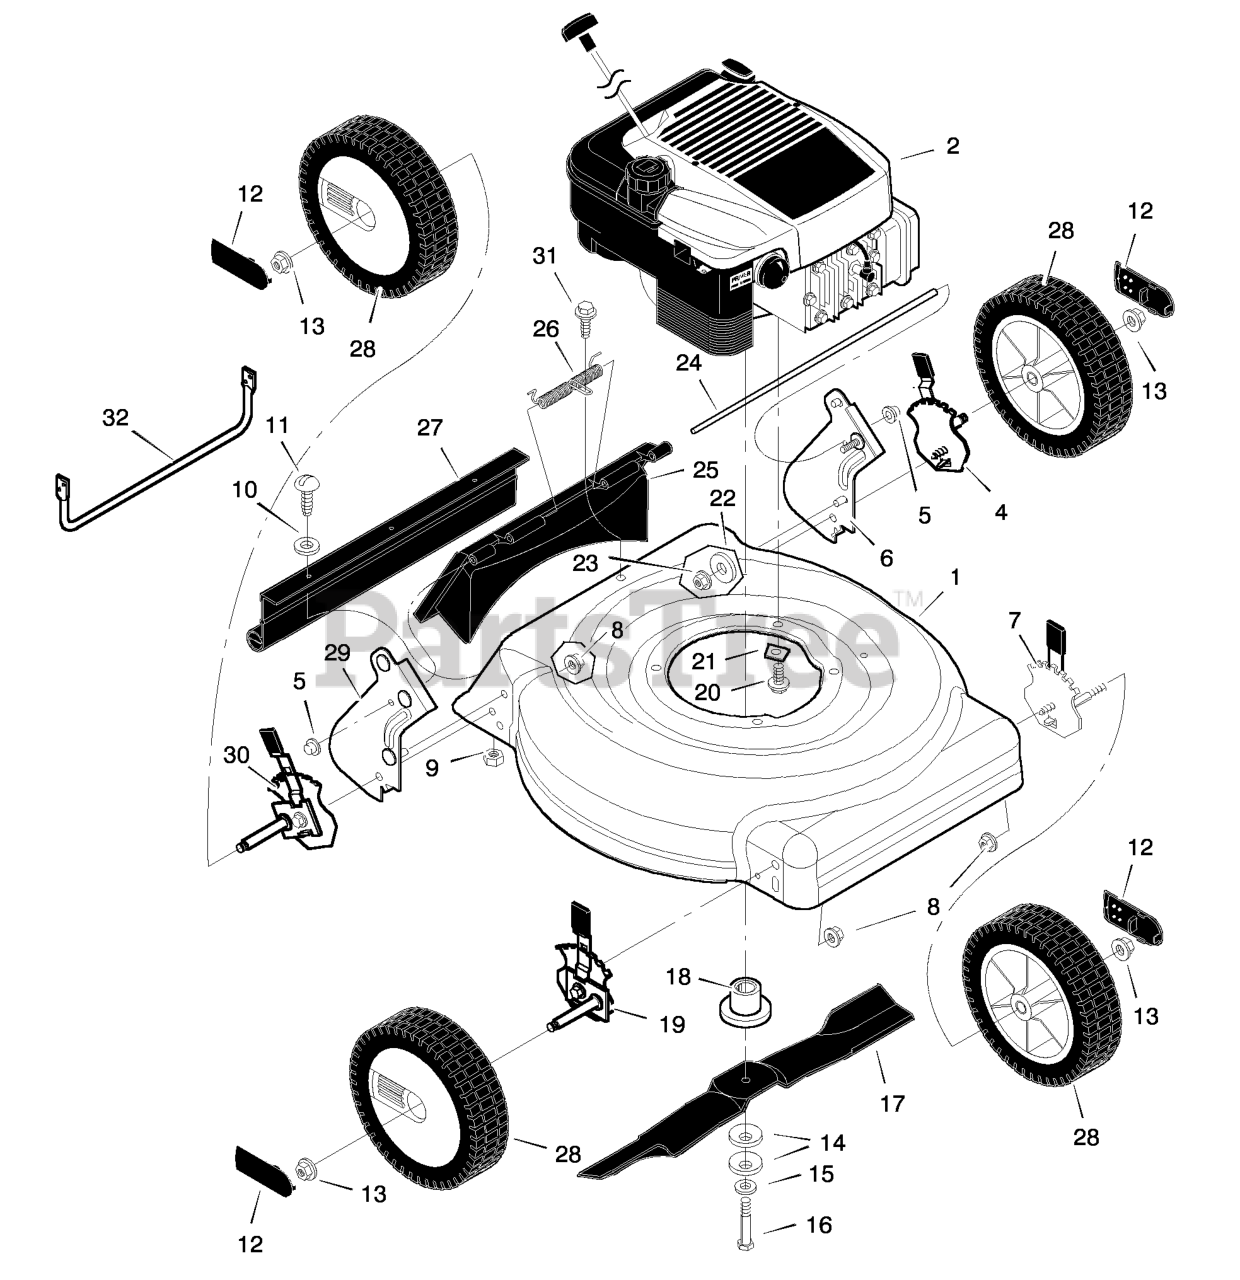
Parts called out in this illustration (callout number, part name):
1	Housing
2	Engine
3	Stop, Rope (Recoil - Start)
4	Adjuster, Left Rear Height
5	Push On Cap
6	Bracket, Left Handle
7	Adjuster, Left Front Height
8	Nut, Flange
9	Nut, Hex
12	Hub Cap
13	Nut, Flange
14	Washer, Belleville
18	Adapter, Blade
19	Adjuster, Right Front Height
20	Bolt, Engine
21	Support, Engine
22	Washer
23	Nut, Flange
24	Rod, Pivot
25	Door, Rear
27	Deflector, Rear
29	Bracket, Right Handle
30	Adjuster, Right Rear Height
32	Guard, Rear
